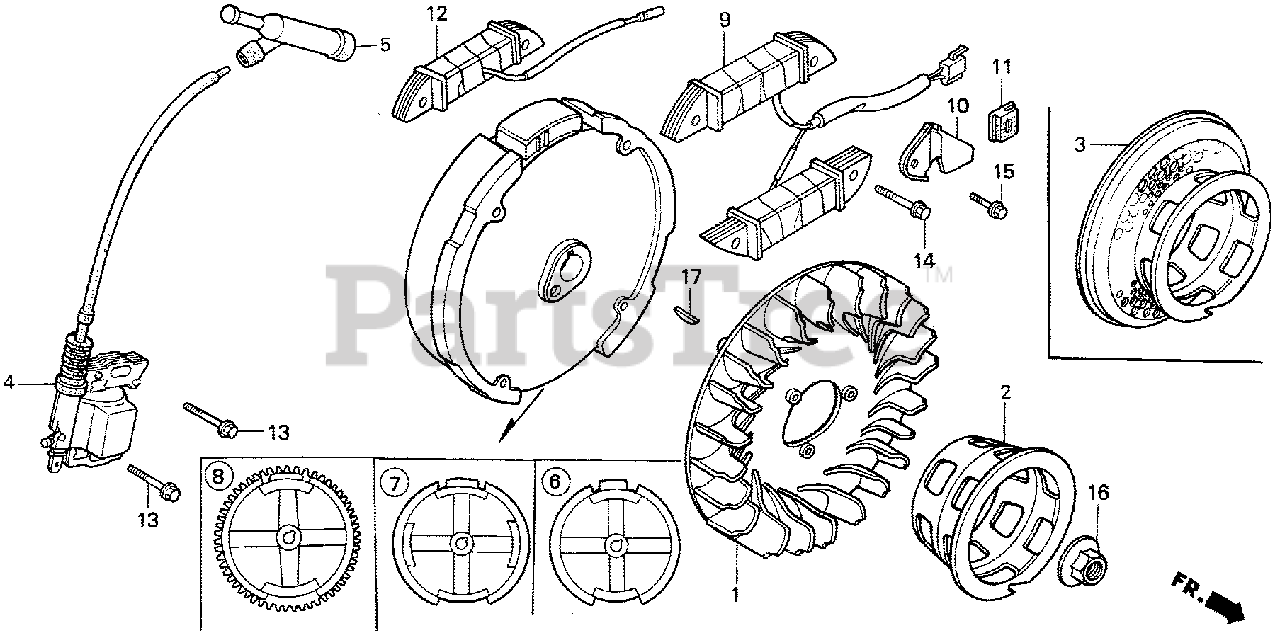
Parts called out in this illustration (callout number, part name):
1	FAN, COOLING
2	PULLEY, STARTER
4	COIL ASSY., IGNITION
5	CAP ASSY., NOISE SUPPRESSOR
8	FLYWHEEL (STARTER MOTOR)
10	CLAMP, WIRE
11	GROMMET, WIRE
12	COIL ASSY., CHARGE
13	BOLT, FLANGE (6X25)
14	BOLT, FLANGE (6X28)
15	BOLT, FLANGE (5X10)
16	NUT, SPECIAL (14MM)
17	KEY, SPECIAL WOODRUFF (25X18)
